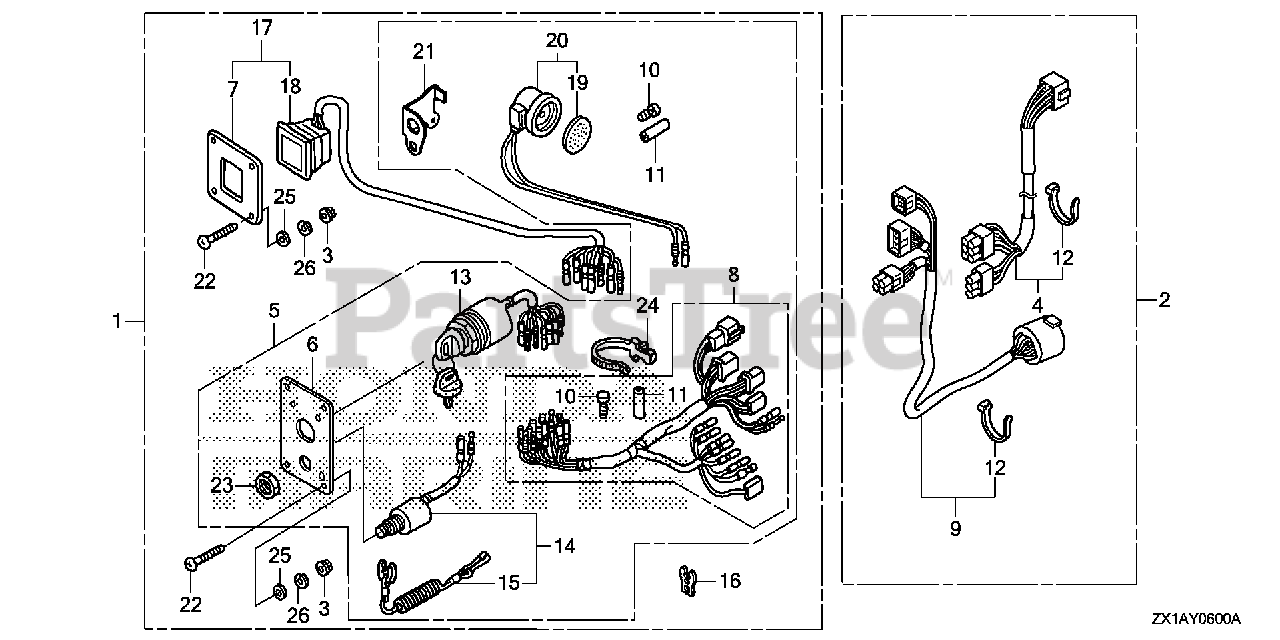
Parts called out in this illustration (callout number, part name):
1	PANEL KIT, SWITCH (4-LED) (B)
2	CABLE SET, PANEL INDICATOR (20FT)
2	CABLE SET, PANEL INDICATOR (25FT)
2	CABLE SET, PANEL INDICATOR (30FT)
3	NUT, FLANGE (5MM) DUAL QTY = (8) (SINGLE)
4	WIRE ASSY., INDICATOR (20FT)
4	WIRE ASSY., INDICATOR (25FT)
4	WIRE ASSY., INDICATOR (30FT)
5	PANEL ASSY., SWITCH
6	PANEL, CONTROL
7	PANEL, CONTROL
8	HARNESS ASSY., SWITCH PANEL
9	CABLE ASSY., SWITCH PANEL (20FT) (NHK MEC)
9	CABLE ASSY., SWITCH PANEL (25FT) (NHK MEC)
9	CABLE ASSY., SWITCH PANEL (30FT) (NHK MEC)
10	PLUG, CONNECTOR (INNER) (TROLLING CONTROL)
11	PLUG, CONNECTOR (OUTER) (ENGINE NO.)
13	SWITCH ASSY., COMBINATION (SINGLE) (DUAL)
14	SWITCH ASSY., EMERGENCY STOP
15	WIRE, EMERGENCY (SINGLE) (DUAL)
16	CLIP, EMERGENCY LOCK
17	PANEL ASSY., INDICATOR (4-LED)
18	LAMP ASSY., INDICATION (4-LED)
19	PLATE, TURN SIGNAL BUZZER DUAL QTY = (2) (SINGLE)
20	BUZZER, WARNING DUAL QTY = (2) (SINGLE)
21	BRACKET, BUZZER
22	SCREW, PAN (5X40) DUAL QTY = (8) (SINGLE)
23	NUT, HEX. (16MM) DUAL QTY = (2) (SINGLE)
24	BAND, WIRE HARNESS (150MM) (NATURAL) DUAL QTY = (2) (SINGLE)
25	WASHER, PLAIN (5MM) DUAL QTY = (8) (SINGLE)
26	WASHER, SPRING (5MM) DUAL QTY = (8) (SINGLE)
